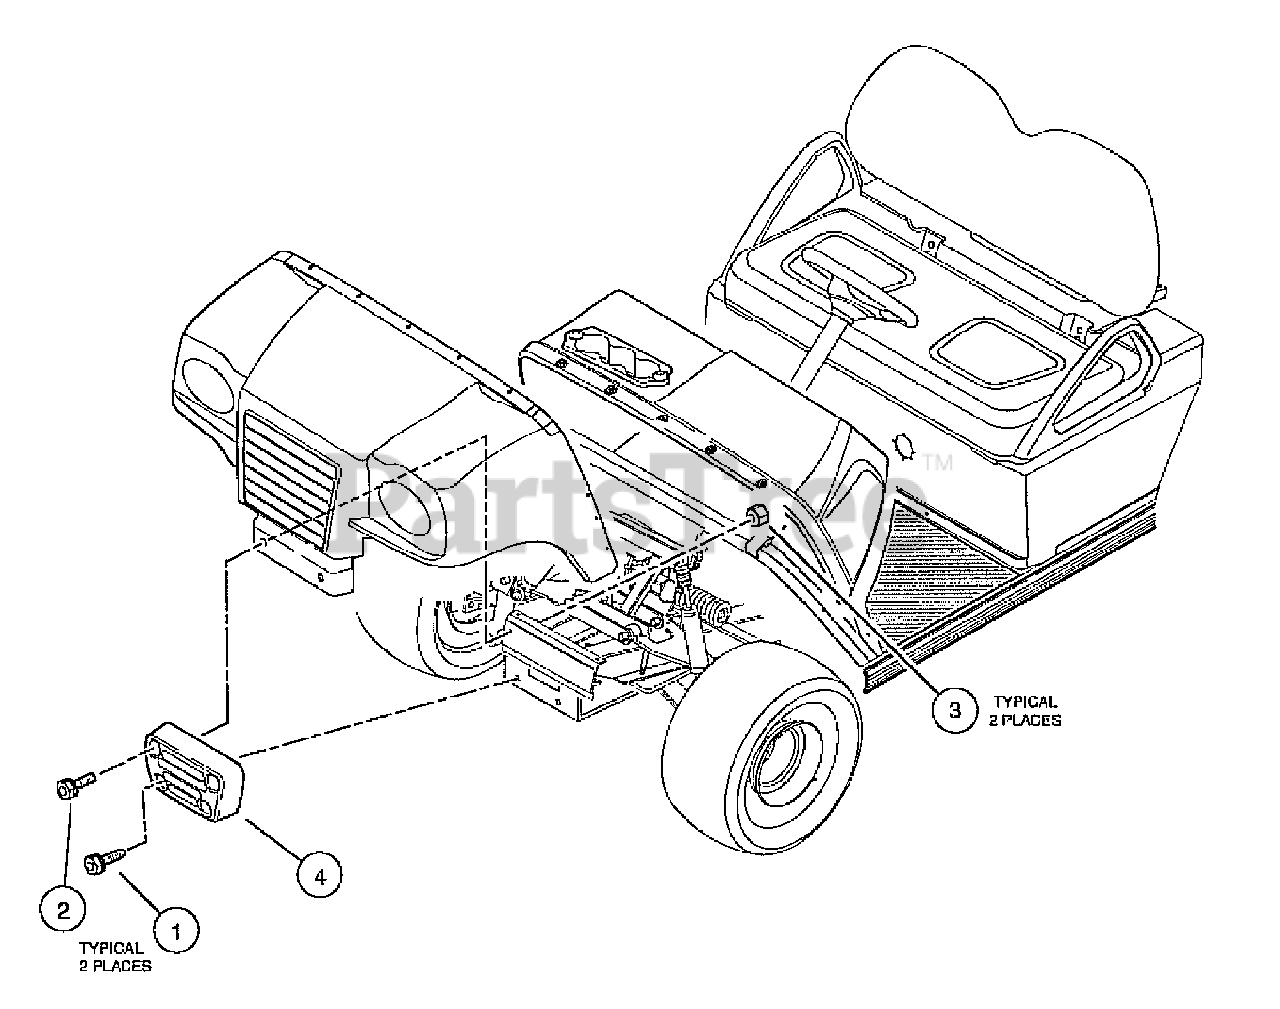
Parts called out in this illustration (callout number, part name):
1	Screw, M8 X 1.25 X 30 Tri, Blk
2	Bolt, Flange Head, MB-1.25 X 40
3	Lock Nut, Fig MB X 1.25 Nylon
4	Bumper, Cast
